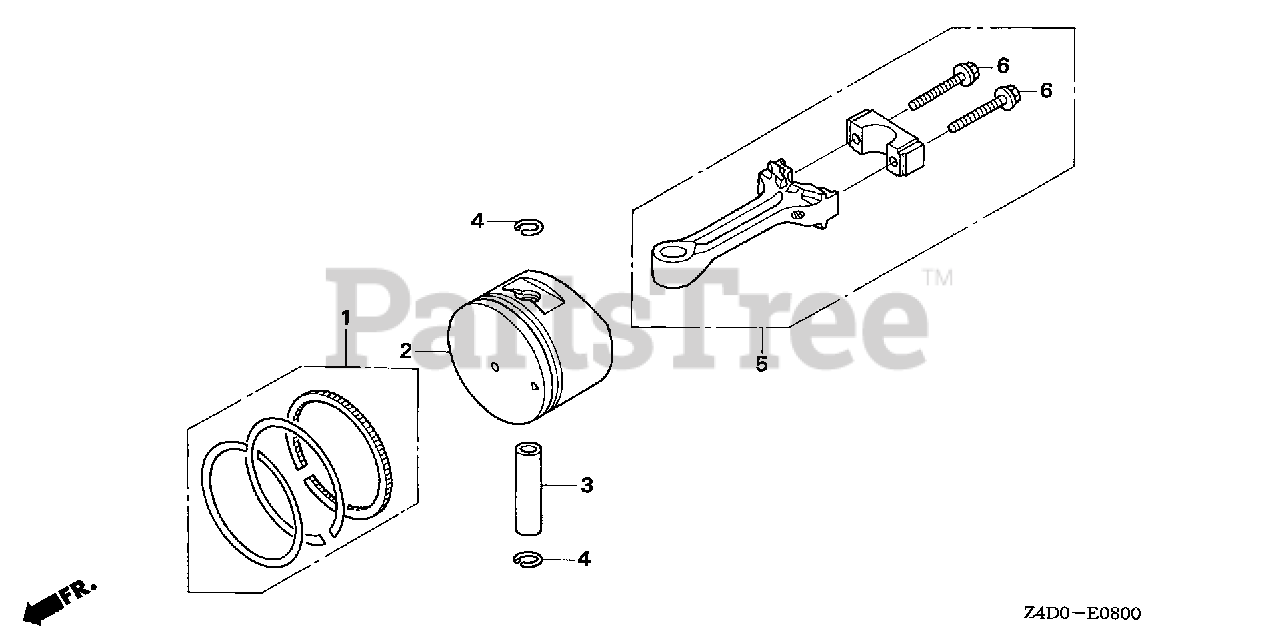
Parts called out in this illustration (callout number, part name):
1	RING SET, PISTON (STD)
2	PISTON (STD)
3	PIN, PISTON
4	CLIP, PISTON PIN (10MM)
5	ROD ASSY., CONNECTING
6	BOLT, CONNECTING ROD
